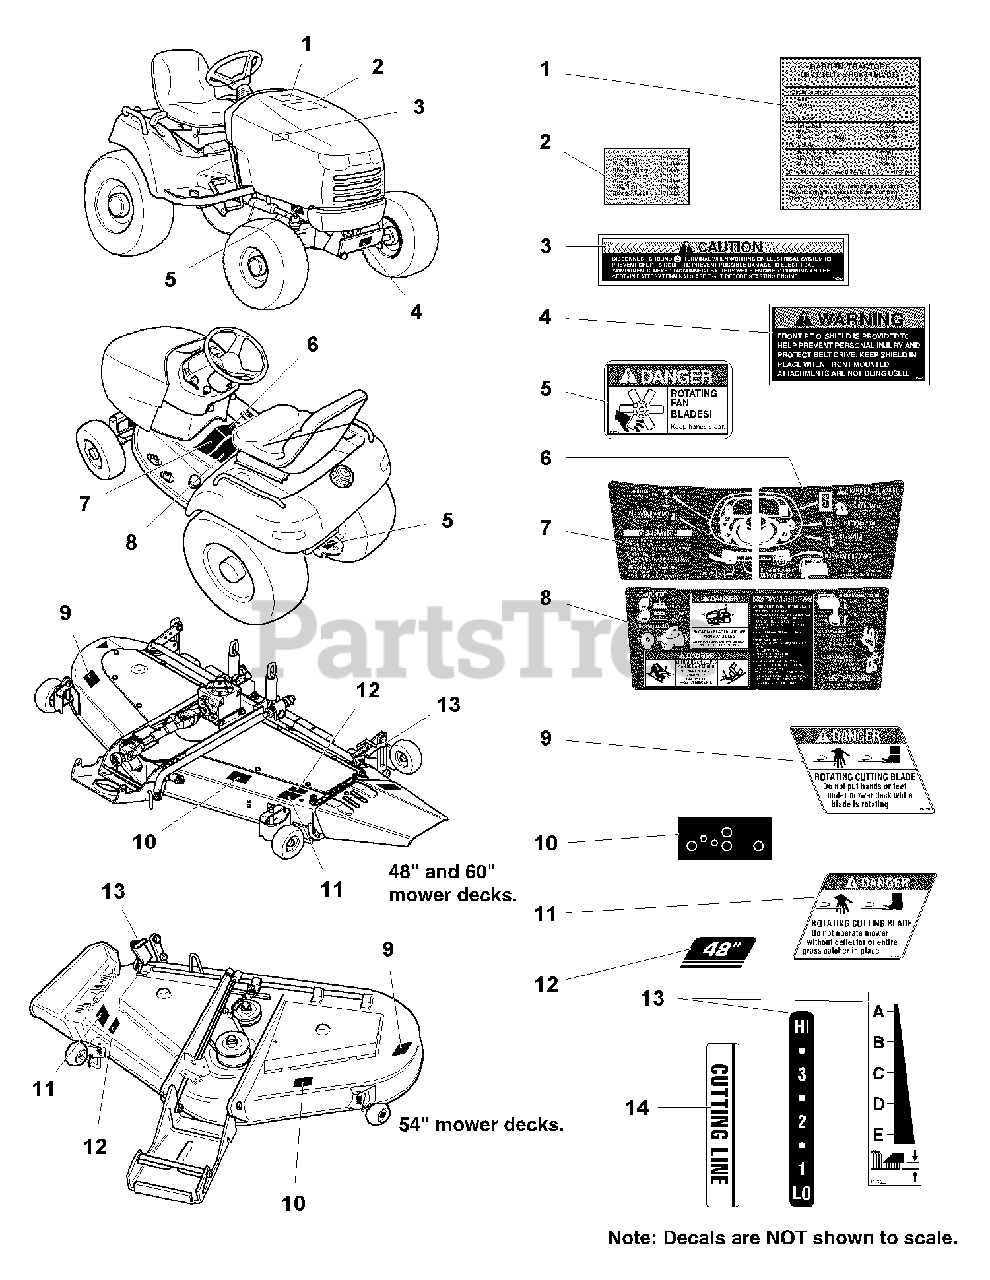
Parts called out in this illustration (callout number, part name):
1	DECAL, Belt, Blade
2	DECAL, Paint (Simplicity & AGCO Models)
2	DECAL, Paint (Massey Ferguson Models)
3	DECAL, Caution, Battery
4	DECAL, Warning, P.T.O. Cover
5	DECAL, Danger, Fan
6	DECAL, Operation, Upper Right Panel
7	DECAL, Operation, Upper Left Panel
8	DECAL, Operation SAFETY, Lower Panel
9	DECAL, Danger (Hand under deck)
10	DECAL, Belt Installation (54" Mower Decks)
10	DECAL, Belt Installation (48" Mower Decks)
10	DECAL, Belt Installation (60" Mower Decks)
11	DECAL, Danger (Chute In Place)
12	DECAL, Cutting Width (48" Mower Decks)
12	DECAL, Cutting Width (60" Mower Decks)
12	DECAL, Cutting Width (54" Mower Decks)
13	DECAL, Cutting Height Indicator, HI - LO (54"Mower Decks)
13	DECAL, Cutting Height Indicator, A-B-C-D-E (48" and 60" Mower Decks)
14	DECAL, Cutting Line
15	DECAL, OPEI (Not serviced)
16	I.D. Plates (Not serviced)
